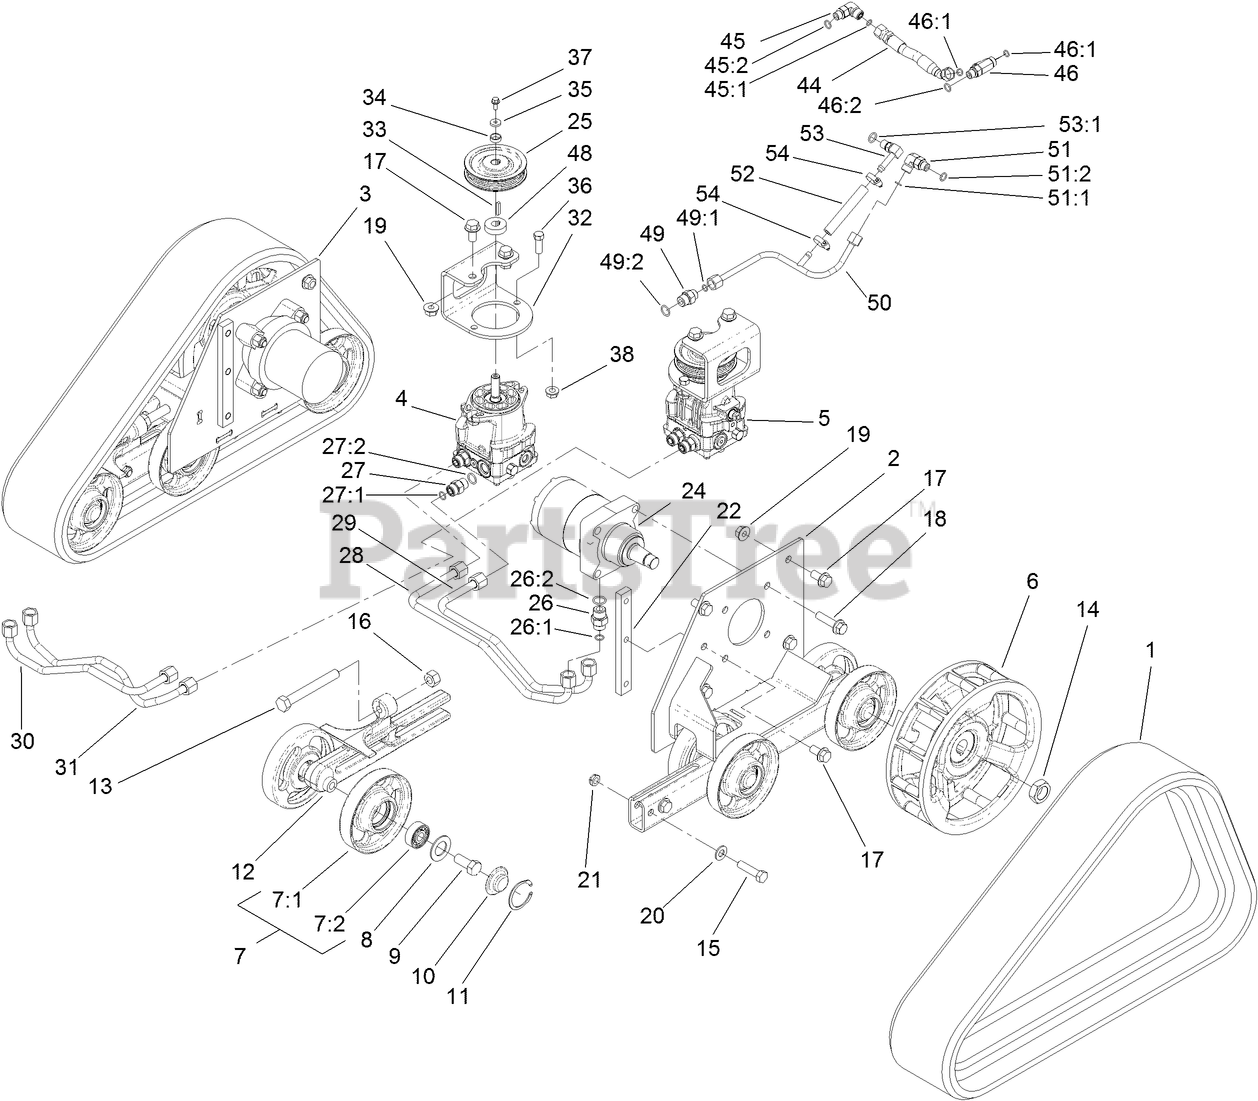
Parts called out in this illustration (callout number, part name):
1	TRACK-RUBBER
2	FRAME-TRACK, LH
3	FRAME-TRACK, RH
4	RH HYD PUMP ASM
5	LH HYD PUMP ASM
6	WHEEL-DRIVE
7	WHEEL-TENSIONER
7:1	WHEEL-TRACK
7:2	BEARING-BALL
8	Gasket-Bogie
9	SCREW-HH
10	CAP-WHEEL, BEARING
11	RING-SNAP, INTERNAL
12	TENSIONER-TRACK
13	SCREW-HH, TAP
14	NUT-LOCK
15	SCREW-HH
16	NUT-HEX
17	SCREW-HHF
18	SCREW-HHF
19	NUT-HHF
20	WASHER-FLAT
21	NUT-LOCK, NI
22	BAR-THREAD
24	HYD WHEEL MOTOR ASM
25	SHEAVE
26	FITTING-STRAIGHT
26:1	O-RING
26:2	O-RING
27	FITTING-STRAIGHT
27:1	O-RING
27:2	O-RING
28	TUBE-HYD
29	TUBE-HYD
30	TUBE-HYD
31	TUBE-HYD
32	BRACKET-MOUNT, PUMP
33	KEY-PUMP
34	BUSHING
35	WASHER
36	SCREW-HH
37	SCREW-HHF
38	NUT-HF
44	HOSE-HYD
45	FITTING-ELBOW, 90 DEG
45:1	O-RING
45:2	O-RING
46	FITTING-TEE
46:1	O-RING
46:2	O-RING
48	SPACER
49	FITTING-STRAIGHT
49:1	O-RING
49:2	O-RING
50	TUBE-HYD
51	FITTING-ELBOW, 90 DEG
51:1	O-RING
51:2	O-RING
53	FITTING-ELBOW, 90
53:1	O-RING
54	CLAMP-HOSE
